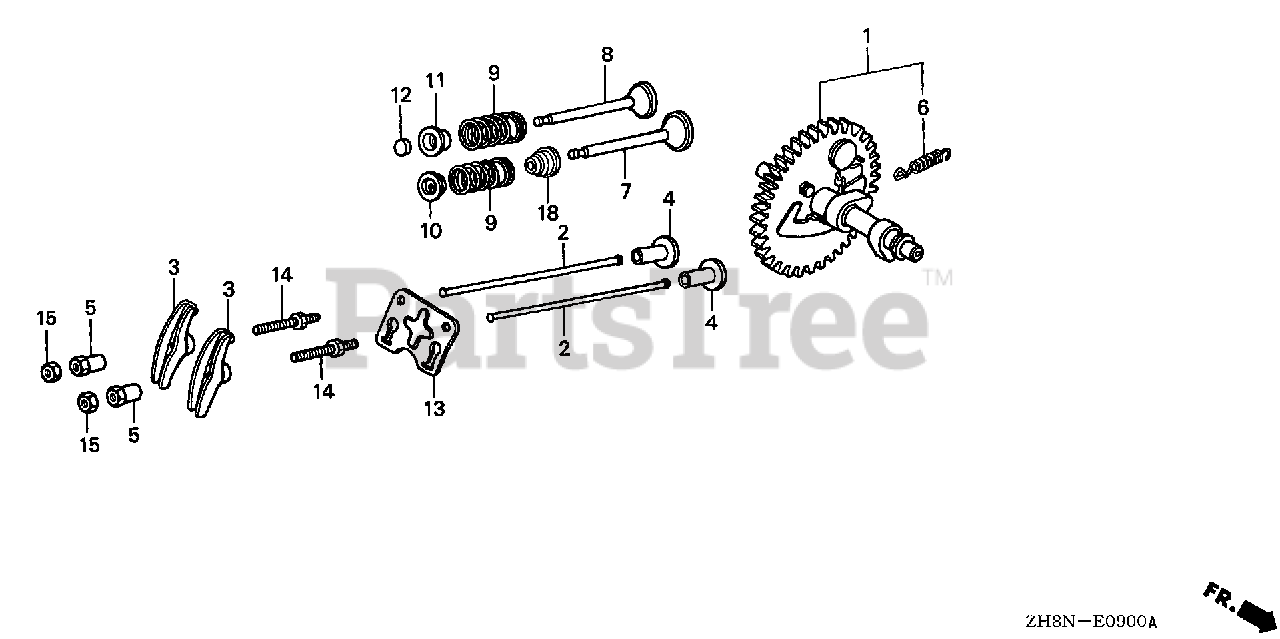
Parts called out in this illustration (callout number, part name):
1	CAMSHAFT ASSY.
2	ROD, PUSH
3	ARM, VALVE ROCKER
4	LIFTER, VALVE
5	PIVOT, ROCKER ARM
6	SPRING, WEIGHT RETURN
7	VALVE, IN.
8	VALVE, EX.
9	SPRING, VALVE
10	RETAINER, IN. VALVE SPRING
11	RETAINER, EX. VALVE SPRING
12	ROTATOR, VALVE
13	PLATE, PUSH ROD GUIDE
14	BOLT, PIVOT (8MM)
15	NUT, PIVOT ADJ.
18	SEAL, VALVE STEM
